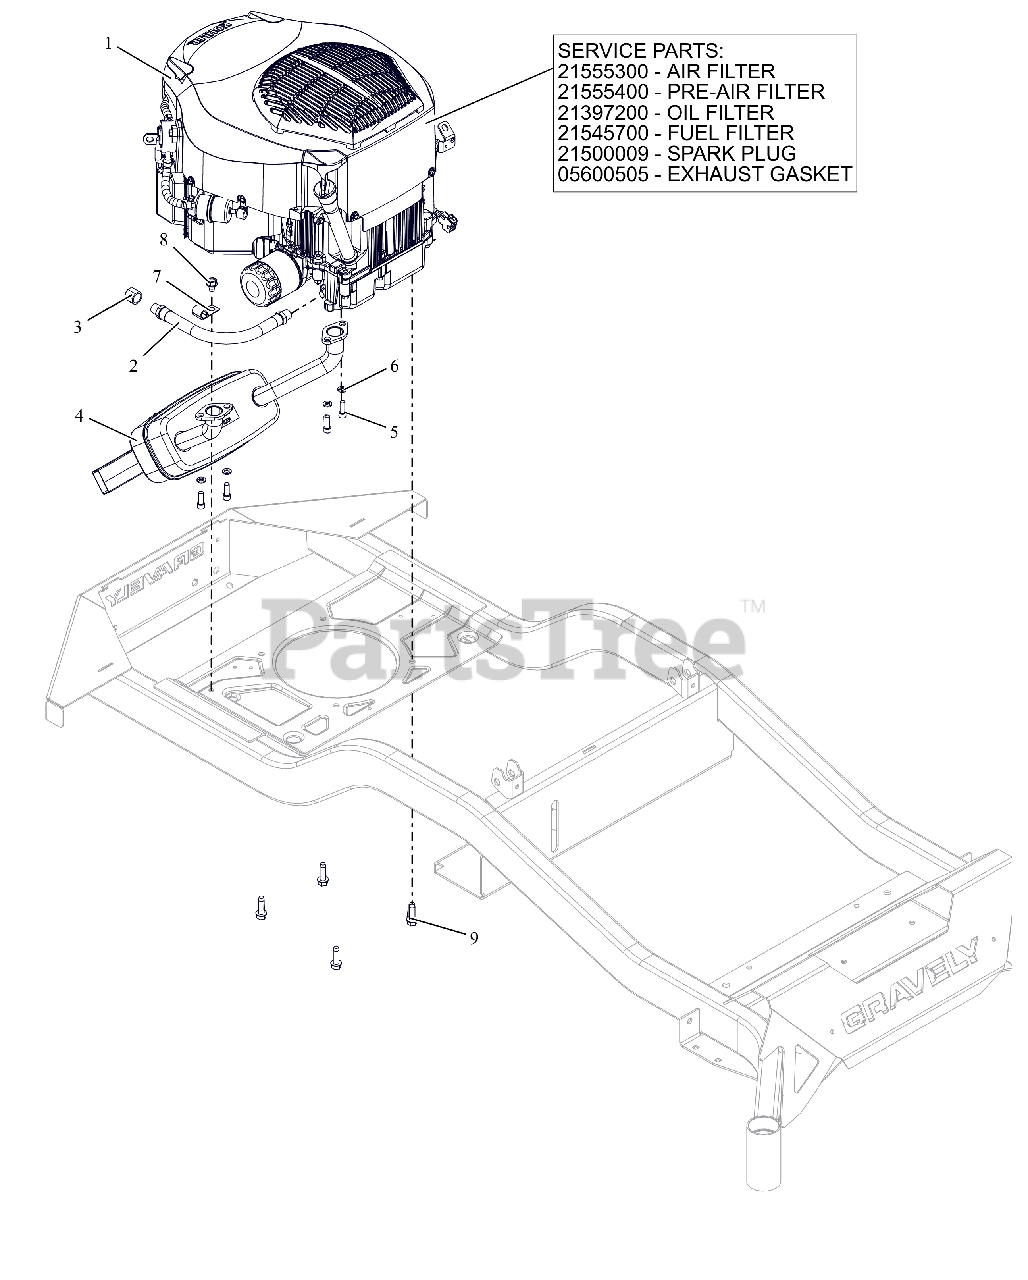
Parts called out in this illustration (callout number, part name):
1	ENGINE, KOHLER - KT740
1	AIR FILTER, KOHLER
1	PRE CLEANER, KOHLER
1	FILTER, OIL - KOH CV20
1	FILTER-FUEL KOHLER COURAGE PRO
1	PLUG, SPARK KOHLER
1	GASKET, MUFFLER KOHLER TWIN
2	HOSE,HYD .38-11-0K M6NO-M6N0
3	PIPE CAP 3/8 NPT FEMALE
4	MUFFLER, KOHLER
5	SCR, SKH .312-18X.875 GR8 ZCC
6	WSHR,LK-REG .312X.078 ZCC
8	SCR,TAP .375-16X.50 HWH TR ZCC
9	SCR,TAP .375-16X1.25HWH TR ZCC
